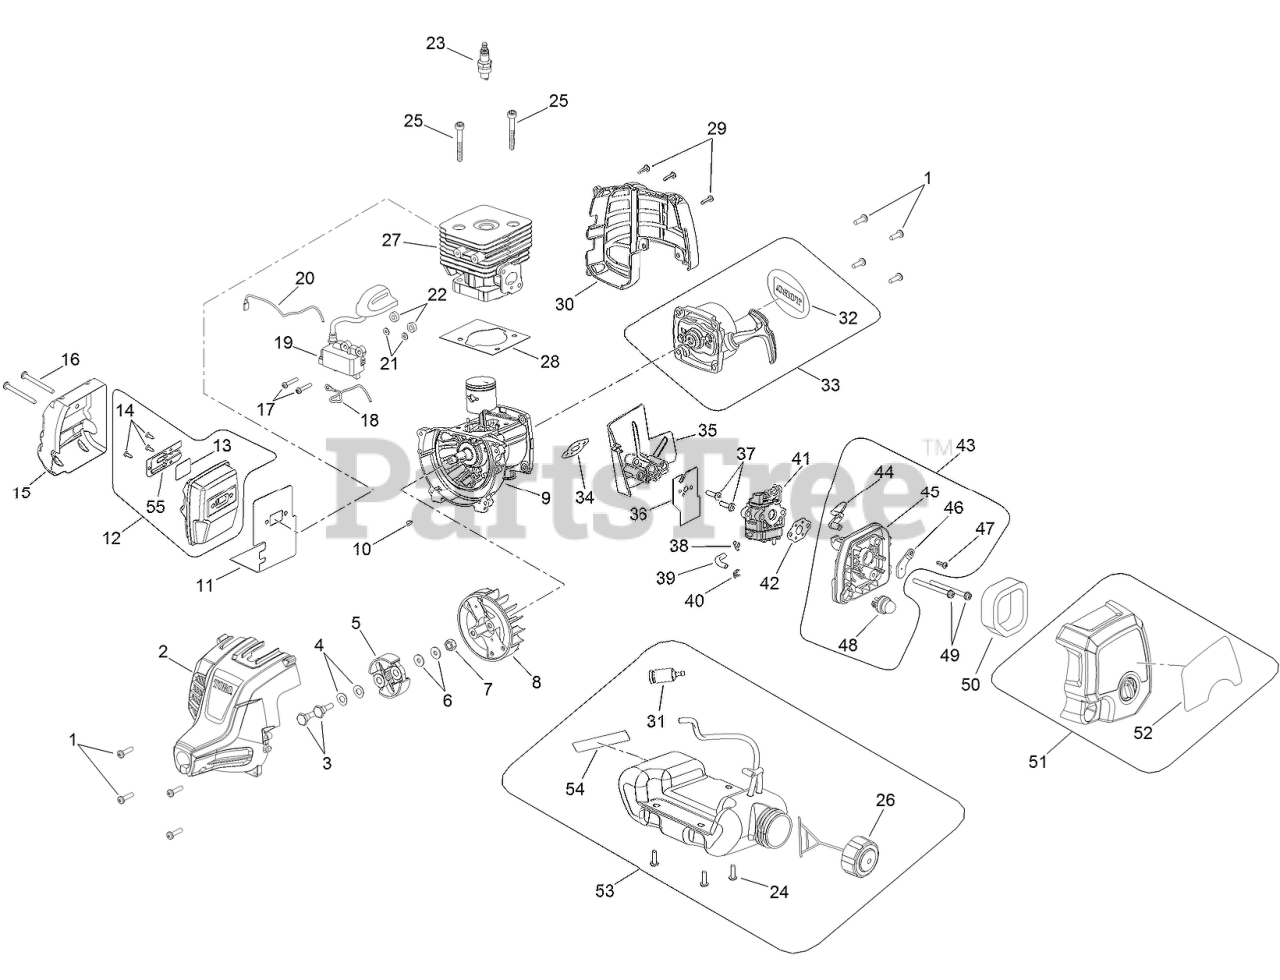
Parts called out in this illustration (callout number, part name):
1	SCREW-PH
2	HOUSING-ENGINE, FRONT
3	SCREW-CLUTCH
4	WASHER-CURVED
5	CLUTCH ASM
7	NUT-ROTOR
9	CRANKCASE ASM
10	KEY-WOODRUFF
11	GASKET-MUFFLER
12	MUFFLER ASM
14	SCREW-PH
15	SHIELD-HEAT
16	SCREW-PH
17	SCREW AND WASHER
18	WIRE-LEAD, RED
19	COIL BOOT ASM
20	WIRE-LEAD, BLACK
23	SPARK PLUG
24	T25 TORX PAN HEAD
25	SCREW-SOCKET HEAD
26	CAP-FUEL
27	CYLINDER
30	HOUSING-ENGINE, REAR
31	FILTER-FUEL
32	PLATE-LOGO
33	RECOIL STARTER AND STARTER CUP ASM
34	GASKET-HEAT DAM
35	HEAT DAM
38	CLIP-HOSE
39	FUEL LINE 45MM
40	CLIP-HOSE
41	CARBURETOR ASM
42	GASKET-CARBURETOR
43	FILTER HOUSING ASM
44	LEVER-CHOKE
45	PLATE-CARBURETOR
46	PLATE-CHOKE
47	SCREW-PH
48	PRIMER ASM
49	T20 TORX CAP SOC HD
50	ELEMENT-FILTER, AIR
51	COVER ASM
52	DECAL-START
53	FUEL TANK AND CAP ASM
54	LABEL-COMBUSTION
55	COVER-TRIMMER
